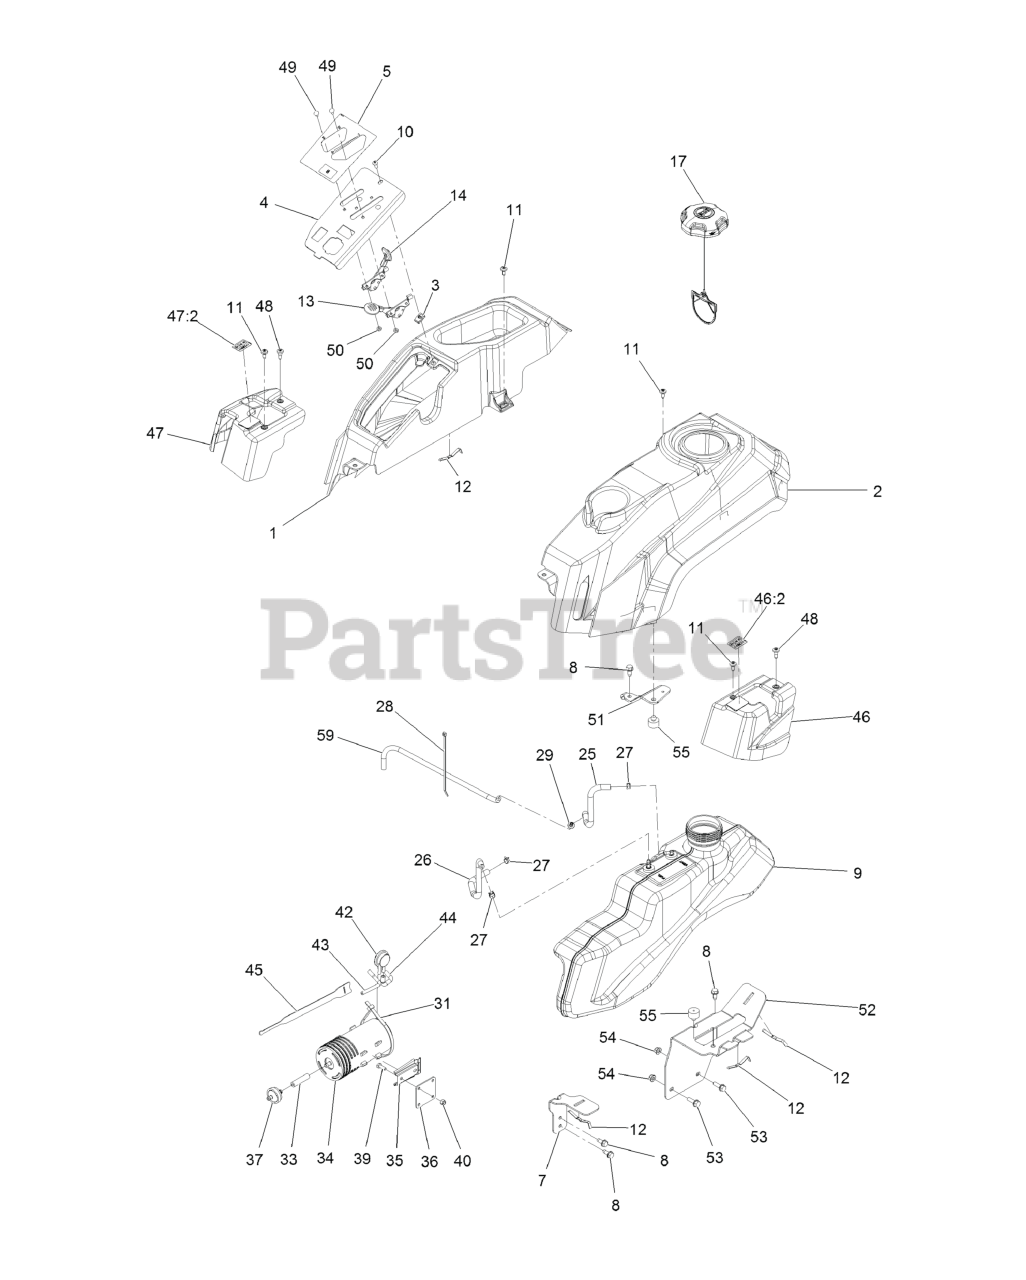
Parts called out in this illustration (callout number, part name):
1	POD-RH, NARROW
2	POD-LH, NARROW
4	PANEL-CONTROL, NARROW
5	DECAL-CONTROL
7	SUPPORT-TANK
8	Screw-HWH 5/16-18 X 3/4 Tf
9	TANK, FUEL
10	SCREW-PRH
11	SCREW-SHOULDER
12	SPRING
13	CABLE-CONTROL, THROTTLE
14	CABLE-CONTROL, CHOKE
17	CAP-FUEL, RATCHETING
25	HOSE-FUEL
26	HOSE-FUEL
27	CLAMP-HOSE
28	TIE-CABLE
29	ADAPTOR-ORIFICE
31	TIE-CABLE
33	HOSE-FUEL
34	CANISTER-CARBON, 800CC
35	BRACKET-CANISTER, CARBON
36	PLATE-ADAPTER
37	FILTER-FUEL, INLINE
39	SCREW-HH
40	NUT-LOCK, NI
42	VALVE-CONTROL, VACUUM
43	HOSE-VENT, FORMED
44	HOSE-VENT, FORMED
45	STRAP-VELCRO, CABLE TIE
46	ASM, POD MC W/DECAL LH
46:2	DECAL-MOTION CONTROL
47	ASM, POD MC W/DECAL RH
47:2	DECAL-MOTION CONTROL
48	SCREW-SHOULDER
49	BOLT-CARR
50	NUT-LOCK, NI
51	BRACKET-CLAMP
52	BRACKET-SUPPORT TANK
53	SCREW-HHF
54	NUT-HF, NI
55	BUMPER-GROMMET
59	HOSE-FUEL
